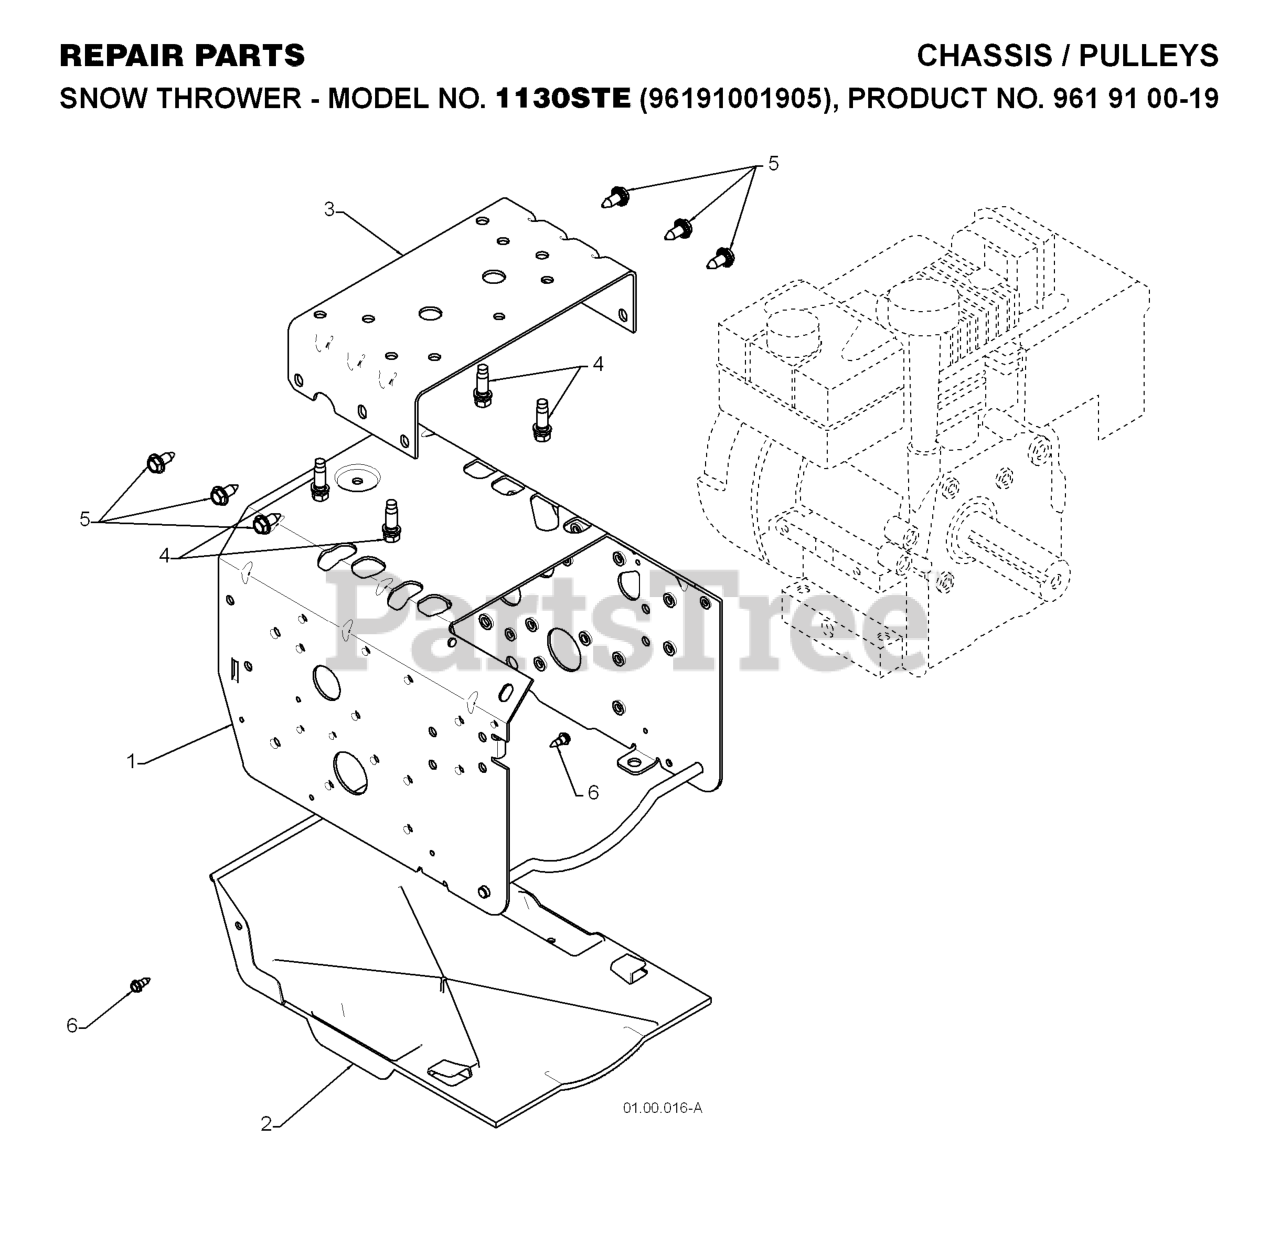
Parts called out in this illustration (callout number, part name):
1	FRAME.WELD.PNT.003BGP
2	PAN.BOTTOM.PLASTIC
3	PLATE.ENGINE.MOUNT.PNT
4	BOLT 3/8-16X1-1/8
5	SELF-TAPPING SCREW 5/16-18X3/4
6	SCREW, HEX HEAD, TAPPING
